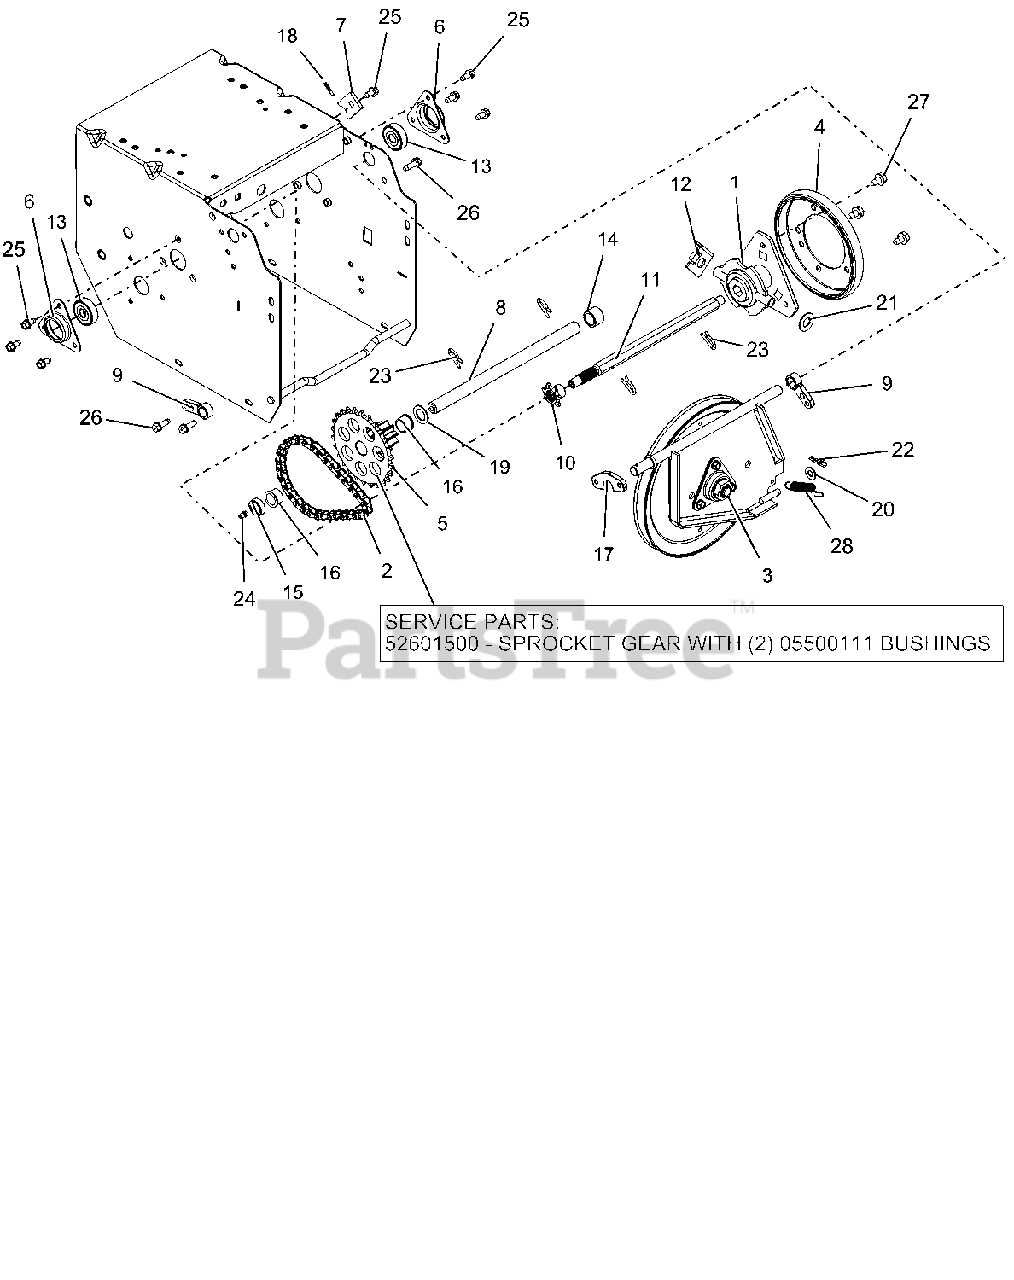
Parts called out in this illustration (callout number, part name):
1	CARRIER, DRIVE DISK
2	CHAIN, ROLLER - #41 w/32 PITCHES
3	PLATE, SWING-ASSY
4	DISC, FRICTION
5	PINION, SPROCKET
5	SPROCKET GEAR
5	BUSHING
6	FLANGE, BRG
7	TAB, ANTI - ROTATION
8	SHAFT, PINION
9	BSHG, SUPPORT - SWING GATE
10	SPROCKET, PINION 7T W/SPLINE
11	SHAFT, HEX W/SPLINE
12	BRKT, FORMED - SHIFT FORK
13	BRG-BALL .437X1.375X.437
14	SPCR, .635 X .880 X .611
15	BSHG, SLV , .635X.880X.305
16	BSHG, FLG .625 X .750 X .500 X .875
17	SPCR, SWING GATE
18	PIN-GRV .125X1.00 TP E
19	WSHR-FL-STL .630X1.005X.062 YWZC
20	WSHR-FL-STL.344X.688X.065YWZC
21	WSHR-FL-STL .505X1.00X.062 YWZC
22	PIN, HAIR INT .08X.18X1.18 YWZC
23	PIN, SPRING CLIP
24	ZERK, FITTING .25X.125 DRIVE IN
25	SCR-TAP .25-20X.50 HWH TR YWZ
26	SCR-TAP .25-20X.75 HWH TR YWZ
27	SCR-TAP .31-18X.50 HWH TR YWZ
28	SPRG, EXTENSION
